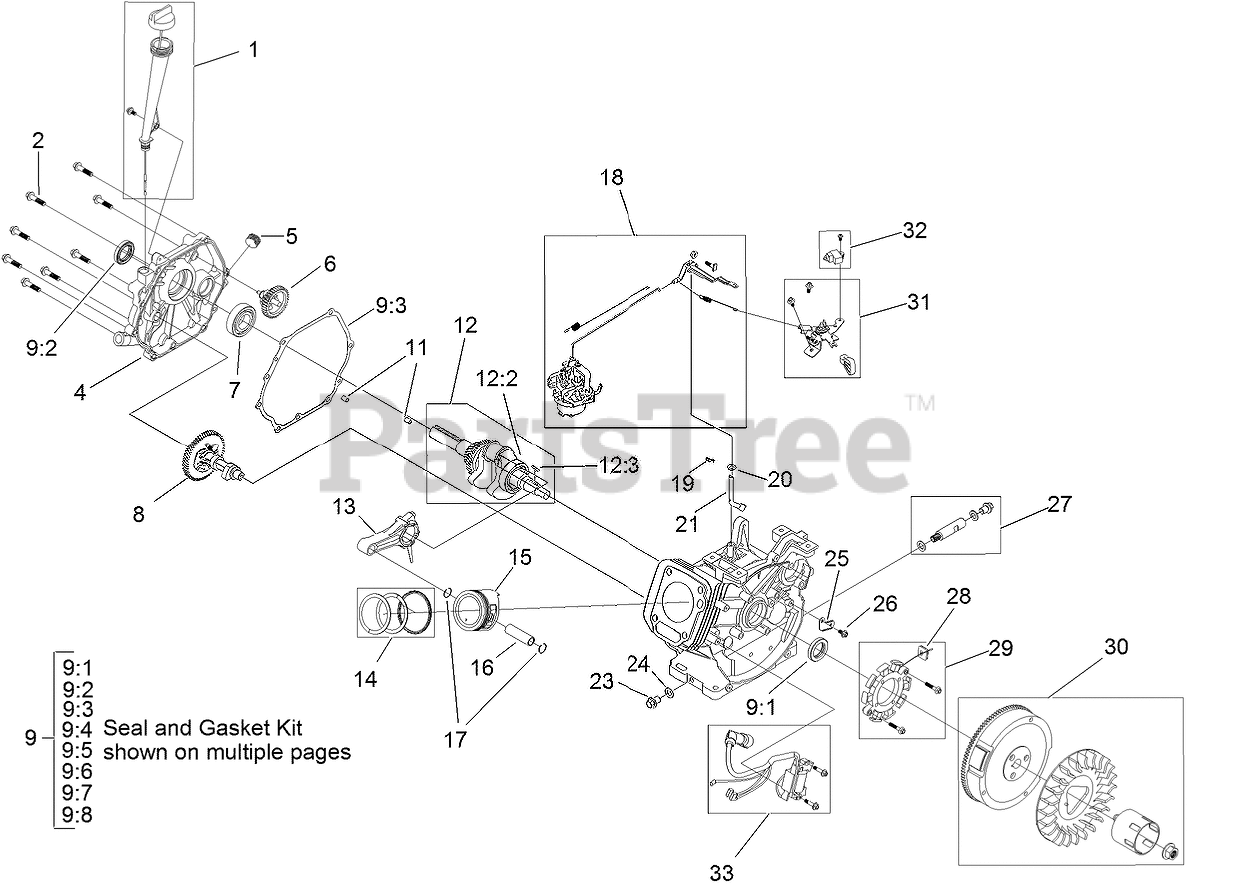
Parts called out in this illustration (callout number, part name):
1	OIL FILL KIT
2	SCREW-HHF
4	COVER-CRANKCASE
5	Plug-Drain
6	GOVERNOR GEAR ASM
7	BEARING-MAIN
8	CAMSHAFT ASM
9	SEAL AND GASKET KIT
9:1	SEAL-OIL
9:2	SEAL-OIL
9:3	GASKET-COVER, CRANKCASE
9:4	GASKET-HEAD, CYLINDER
9:5	GASKET-COVER, VALVE
9:6	GASKET-EXHAUST
9:7	GASKET-CARBURETOR
9:8	GASKET-CARBURETOR
11	PIN-DOWEL
12	CRANKSHAFT ASM
12:2	BEARING-MAIN
12:3	KEY-WOODRUFF
13	CONNECTING ROD ASM
14	SET-RING, PISTON
15	PISTON
16	PIN-PISTON
17	CLIP-PIN, PISTON
18	COMPLETE GOVERNOR KIT
19	PIN-HAIR
20	WASHER-PLAIN
21	SHAFT-GOVERNOR
23	SCREW-HHF
24	WASHER-PLAIN
26	SCREW-HHF
27	DRAIN PLUG KIT
28	GROMMET-RUBBER
29	STATOR KIT
30	FAN AND FLYWHEEL KIT
31	THROTTLE CONTROL KIT
32	KILL SWITCH KIT
33	IGNITION KIT
